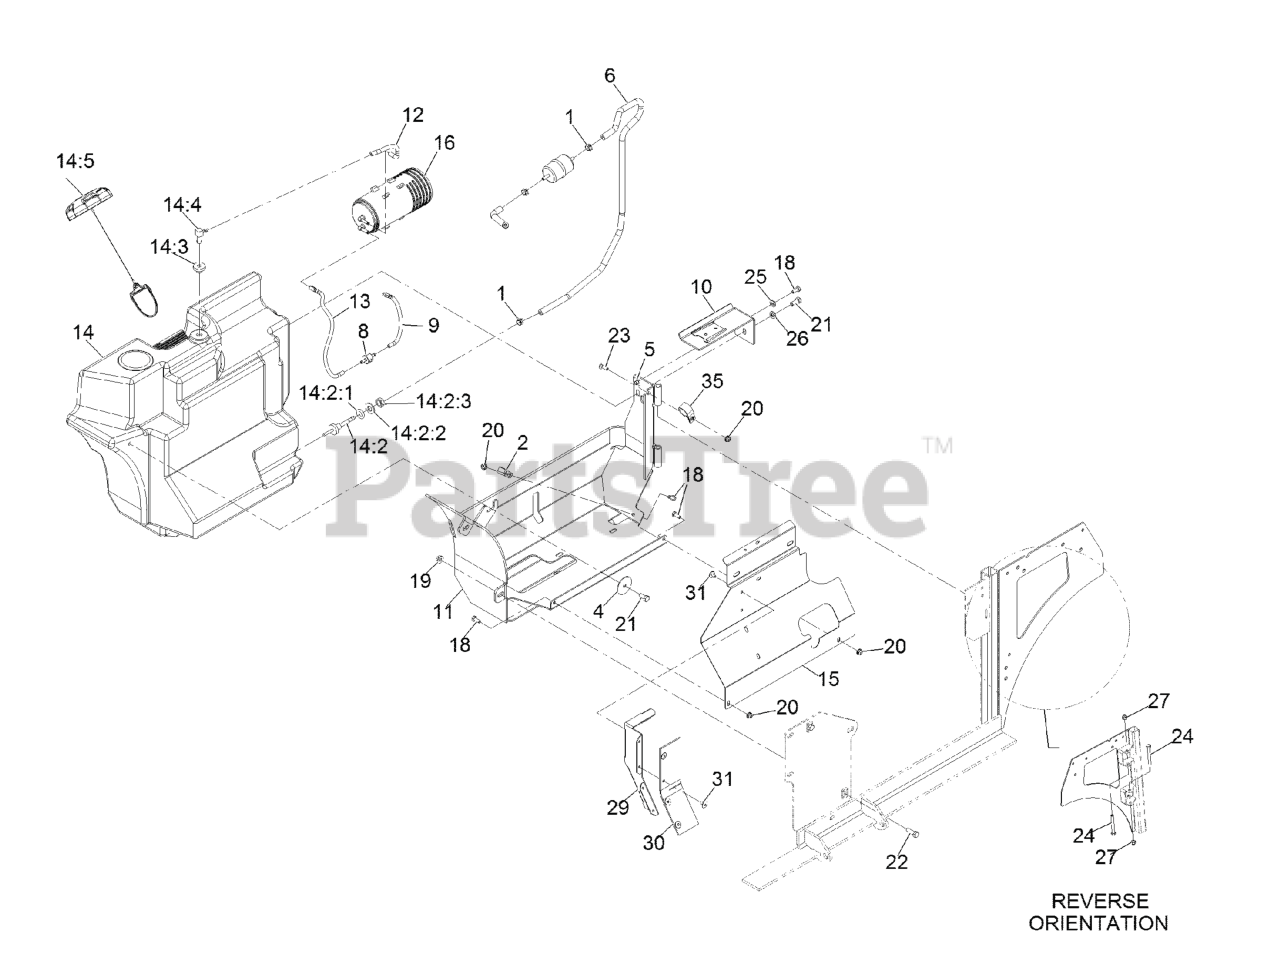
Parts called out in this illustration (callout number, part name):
1	CLAMP-HOSE
2	CLIP-LOOM
6	HOSE-FUEL
8	VALVE-CHECK, VACUUM
9	HOSE-VENT, FORMED
10	CANISTER BRACKET ASM
11	TANK FRAME ASM
12	HOSE-VENT, FORMED
13	HOSE-VENT, FORMED
14	FUEL TANK ASM
14:2	FITTING-FUEL, BULKHEAD
14:2:1	O-RING,BULKHEAD FITTING
14:2:2	WASHER-FLAT
14:2:3	NUT-JAM
14:3	BUSHING
15	PANEL-TANK SHIELD
16	CANISTER-CARBON, 800CC
18	SCREW-HH
21	SCREW-HH
22	SCREW-HH
23	BOLT-CARR
24	SCREW-HH
25	WASHER-FLAT
26	WASHER-PLAIN
27	NUT-LOCK, NI
29	DEFLECTOR-AIR
30	FLAP-RUBBER
31	RIVET-POP
35	R-CLAMP
